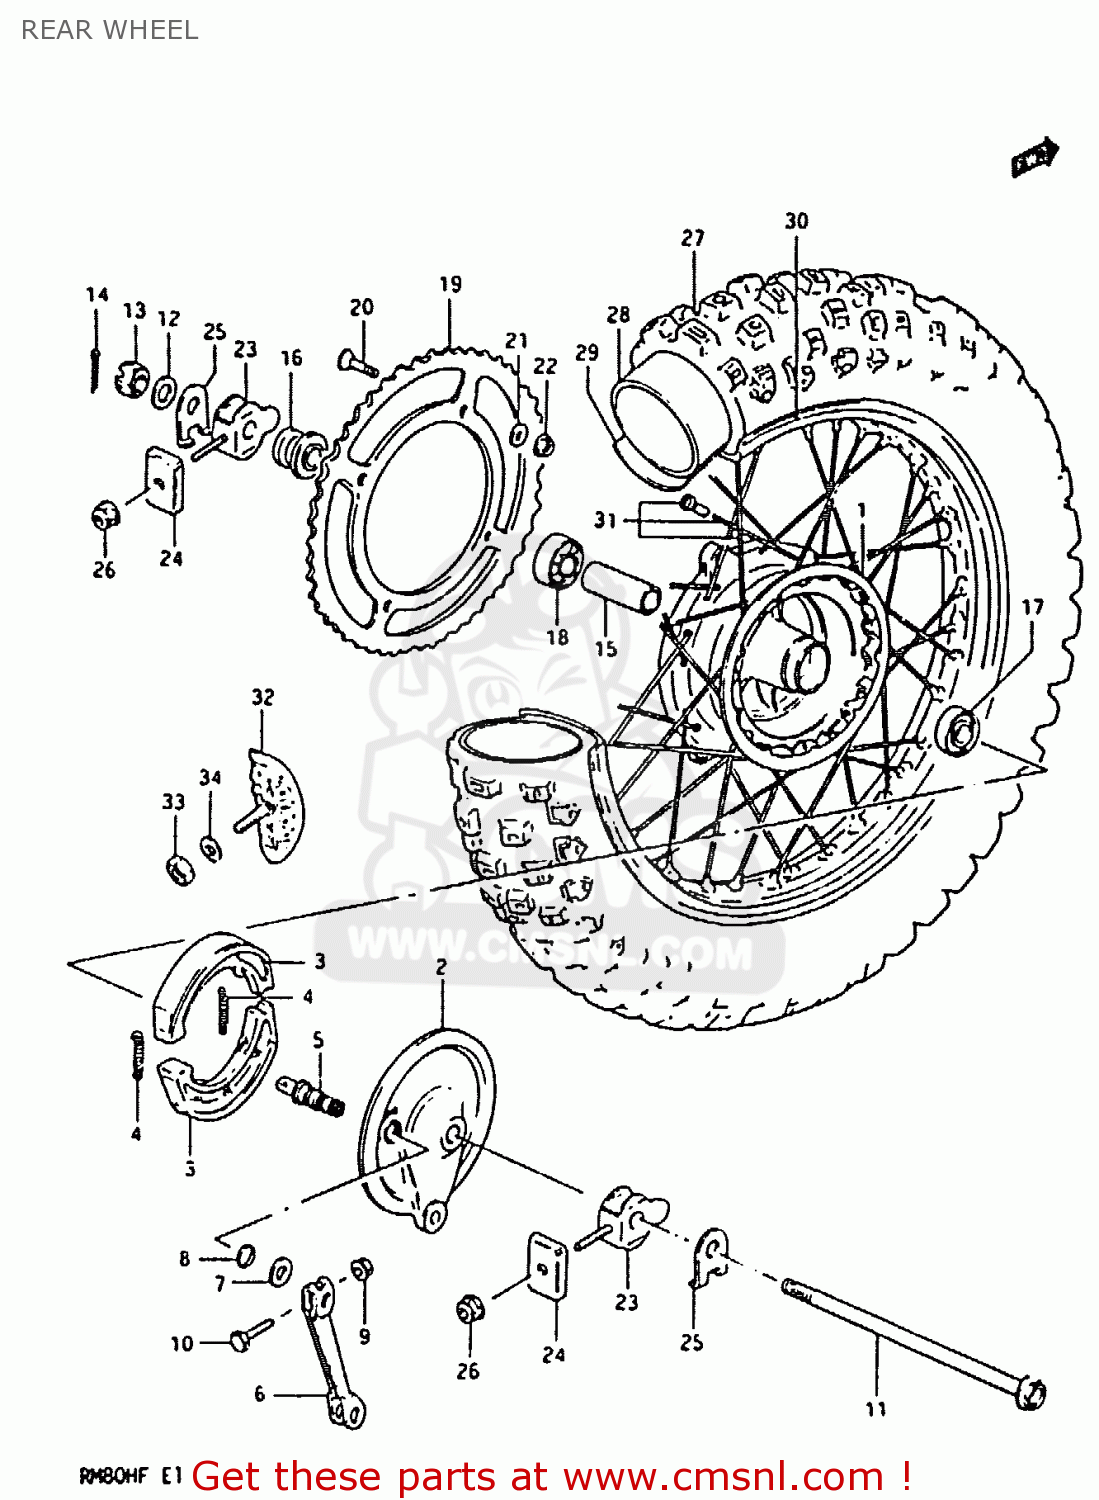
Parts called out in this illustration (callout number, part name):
1	DRUM, REAR HUB
2	PANEL, REAR HUB
3	SHOE,BRAKE
4	SPRING, BRAKE SHOE
5	CAM,FRONT BRAKE
6	LEVER,RR BRAKE CAM
7	WASHER(12.5X20X1)
8	O RING(D:2.5,ID:11.4)
9	NUT
10	BOLT
11	AXLE,REAR
12	WASHER
13	NUT
14	COTTER PIN
15	SPACER(15.3X21.7X77)
16	SPACER,L
17	BEARING
18	BEARING
19	SPROCKET, REAR
20	SCREW(8X33.5)
21	WASHER
22	NUT
23	ADJUSTER,CHAIN
24	ADJUSTER,CHAIN
25	WASHER
26	NUT
27	TIRE, REAR (3.50*18)
28	TUBE ASSEMBLY,WHEEL,INNER
29	PROTECTOR,INNER TUBE
30	RIM, WHEEL (1.85*18 AL) GOLD
31	SPOKE ASSY,RR WHEEL
32	STOPPER,BEAD
33	NUT
34	WASHER
